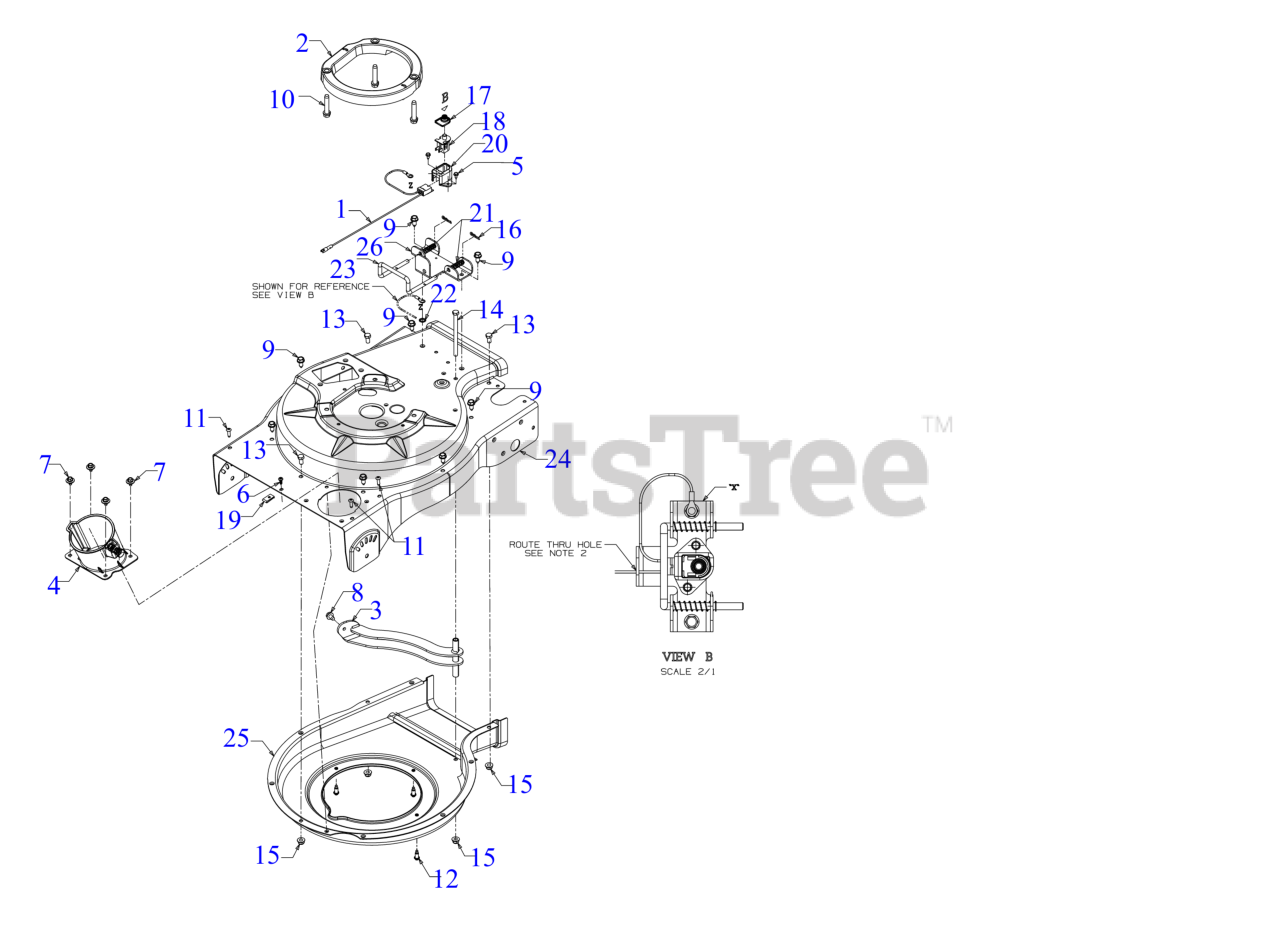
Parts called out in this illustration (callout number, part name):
1	WIRE HARNESS ASSEMBLY
2	ENGINE SPACER ASSEMBLY
3	SCREEN ASSEMBLY (POWDER BLACK)
4	HOSE ADAPTER BASE ASSEMBLY
5	HEX SCREW AB-TAP #10 x .50
6	SCREW #10-16 x 0.500
7	SCREW 1/4-20 x .50
8	SCREW 5/16-18 x .500
9	SCREW 5/16-12 x .750
10	SCREW 3/8-16 x 1.875
11	SCREW #12-16 x .750
12	SCREW .30 x .46
13	SCREW 5/16-18X .625 GR5
14	SCREW 5/16-18 x 4.5 GR5
15	FLANGE LOCK NUT 5/16-18
16	COTTER PIN .072 DIA. 1.13 LG
17	SWITCH COVER
18	SNAP MOUNT SWITCH (GREY)
19	U-TYPE SPEED NUT
20	SWITCH COVER
21	COMPRESSION SPRING
26	MOUNTING BRACKET (POWDER BLACK)
